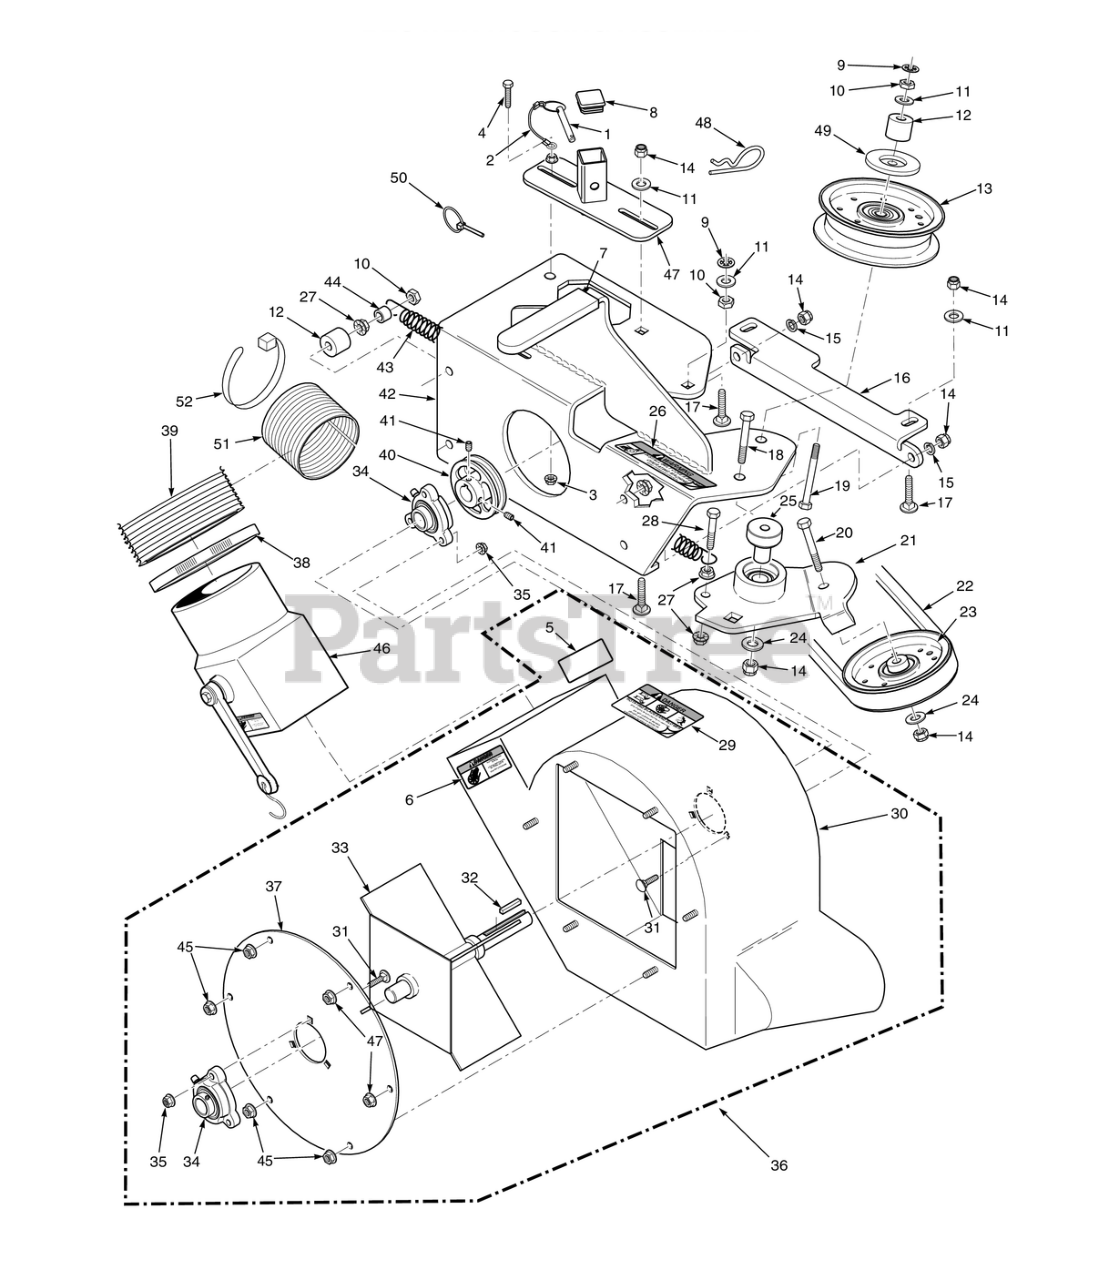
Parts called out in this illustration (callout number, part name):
1	Pin, Ring 1/2 x 2-1/4"
2	Lanyard, Deck Height Pin
3	NUT, 1/4-20 SERRATED FLANGE HEX HEAD
4	NUT, 1/4-20 SERRATED FLANGE HEX HEAD
5	Decal, Blower
6	Decal, Rotating Blower
7	Grip, Deck Latch Lever
8	Cap, Square Vinyl
9	Nut, Push-On - 3/8" Dia.
10	Bolt, Hex Head 3/8-16 x 1" Ser. Flg.
11	Flatwasher, 3/8" Special (.391 x .938 x .105)
12	SPACER, J-PULL ROD
13	Pulley, Idler 3-1/2" Dia. - 52"
14	HEX NUT, ELASTIC STOP LOCK, 3/8-16
15	Lockwasher, 3/8" Spring, Kawasaki FX / FS
16	Plate, Catcher Mounting
17	Bolt, RDHD Carr. 3/8-16 x 1-1/2 (52" & 61")
18	Bolt, Hex Head 3/8-16 x 3" - 52"
19	Bolt, Hex Head 3/8-16 x 3-1/2" Full Thread
20	Bolt, Hex Head 3/8-16 x 1-3/4" (Kohler EFI)
21	Idler Arm Assembly - 52"
22	Belt, GC-SCZ-48V / STCII-48V
22	Belt, GC-SCZ-52V / STCII-52V
23	Pulley, 3-1/2" O.D., GC-STT 52"
24	Flatwasher, 3/8 (.391 x .938 x .105 HD) Grade 8
25	Pivot, Idler - Short
26	Decal, Warning - Belt Cover
27	NUT, 3/8-16 SERRATED FLANGE HEX HEAD
28	Bolt, Hex Head 3/8-16 x 1-1/2" Grade 8 Black
29	Decal, Danger
30	Blower Housing Weldment w/Decals
31	Bolt, 5/16-18 x .75 RHSN Carriage
32	KEY 1/4 X 1/4 X 1 1/2"(FOR 1" CRANKSHAFT
33	Fan Weldment
34	Bearing Assembly
35	HEX NUT, ELASTIC STOP LOCK, 5/16-18
36	Blower Housing Assembly, GC-STT
37	COVER, BLOWER HOUSING
38	Clamp, 8-5/8" Max Dia. (61")
39	Hose, 8.00" Dia. x 53" Long
40	Pulley, 4-3/4" O.D. - 1" Bore
41	Setscrew, Hex Socket Knurl Cup Pt. 5/16 - 18 (nylock)
42	Frame, Blower Mount
43	Spring, Helper (61" Cutter Deck Only)
44	Spacer, Deck Assist
45	Nut, Serrated Flange 5/16-18 (Right Front Engine Mounting, Briggs and Kohler Only)
46	Adapter, Blower GC-STC,
47	Receiver Weldment, Mount Post - 61"
48	Hair Pin Cotter, .177" x 3-1/4"
49	Quick Pin, 5/16" Dia.
50	Quick Pin, 5/16" Dia.
51	Hose, 8" Dia. x 24" Split
52	Cable Tie, .345 X 31.5 Black
